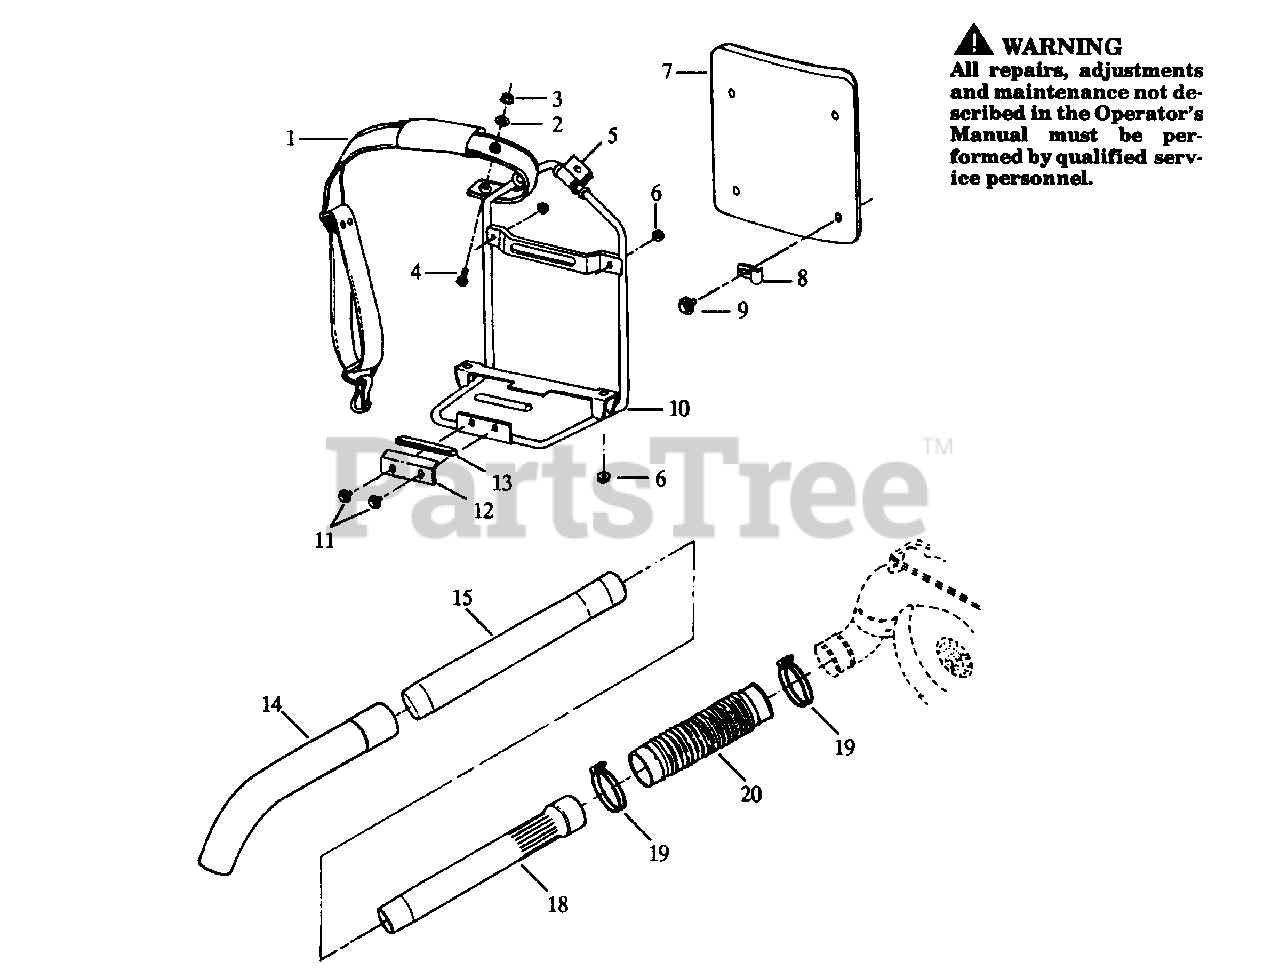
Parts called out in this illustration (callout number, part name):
1	Shoulder Strap
5	Band Support
7	Knapsack Pad
8	Knapsack Pad Fitting
10	Knapsack Frame
12	Tank Stay
13	Absorber
14	Bend Pipe
15	Middle Pipe
18	Base Pipe
19	Hose Band
20	Flexible Pipe
